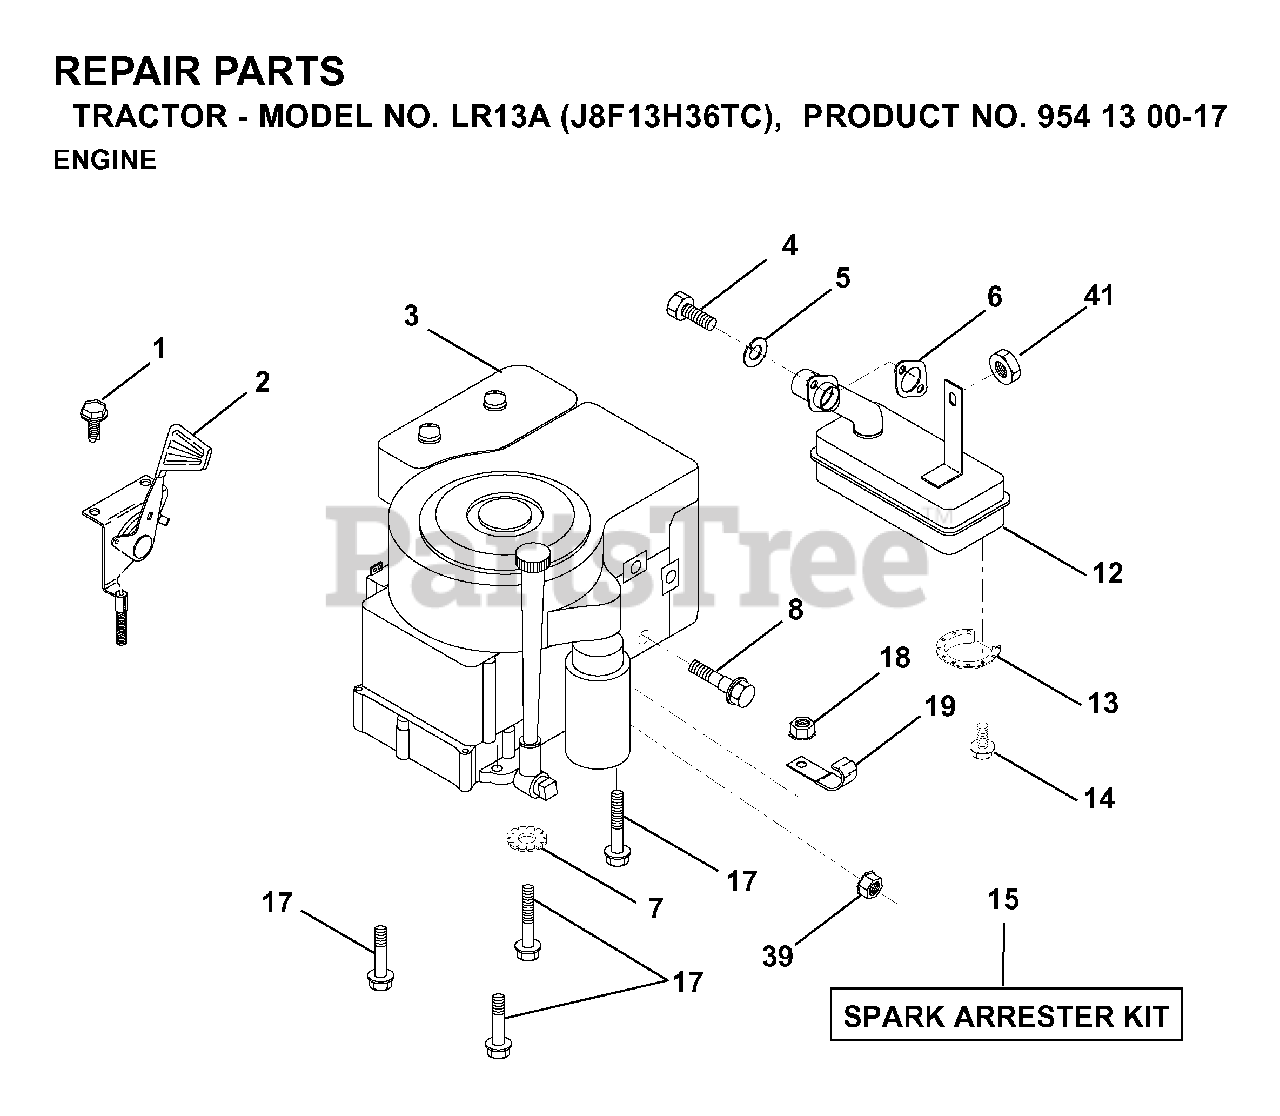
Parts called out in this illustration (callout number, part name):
1	SCREW LT
2	CONTROL THROTTLE
5	LOCKWASHER
6	REPL BY 532 27 22-93
7	LOCKWASHER
8	SHOULDER BOLT ST
13	DEFL MUFFLER LTV
14	SCREW
15	ARRESTER SPARK (OPTIONAL)
17	SCREW LT
19	CLIP T
39	NUT FLANGE 1/4-20 STARTER NUT
41	NUT LOCK HEX FLANGE 5/16-18
